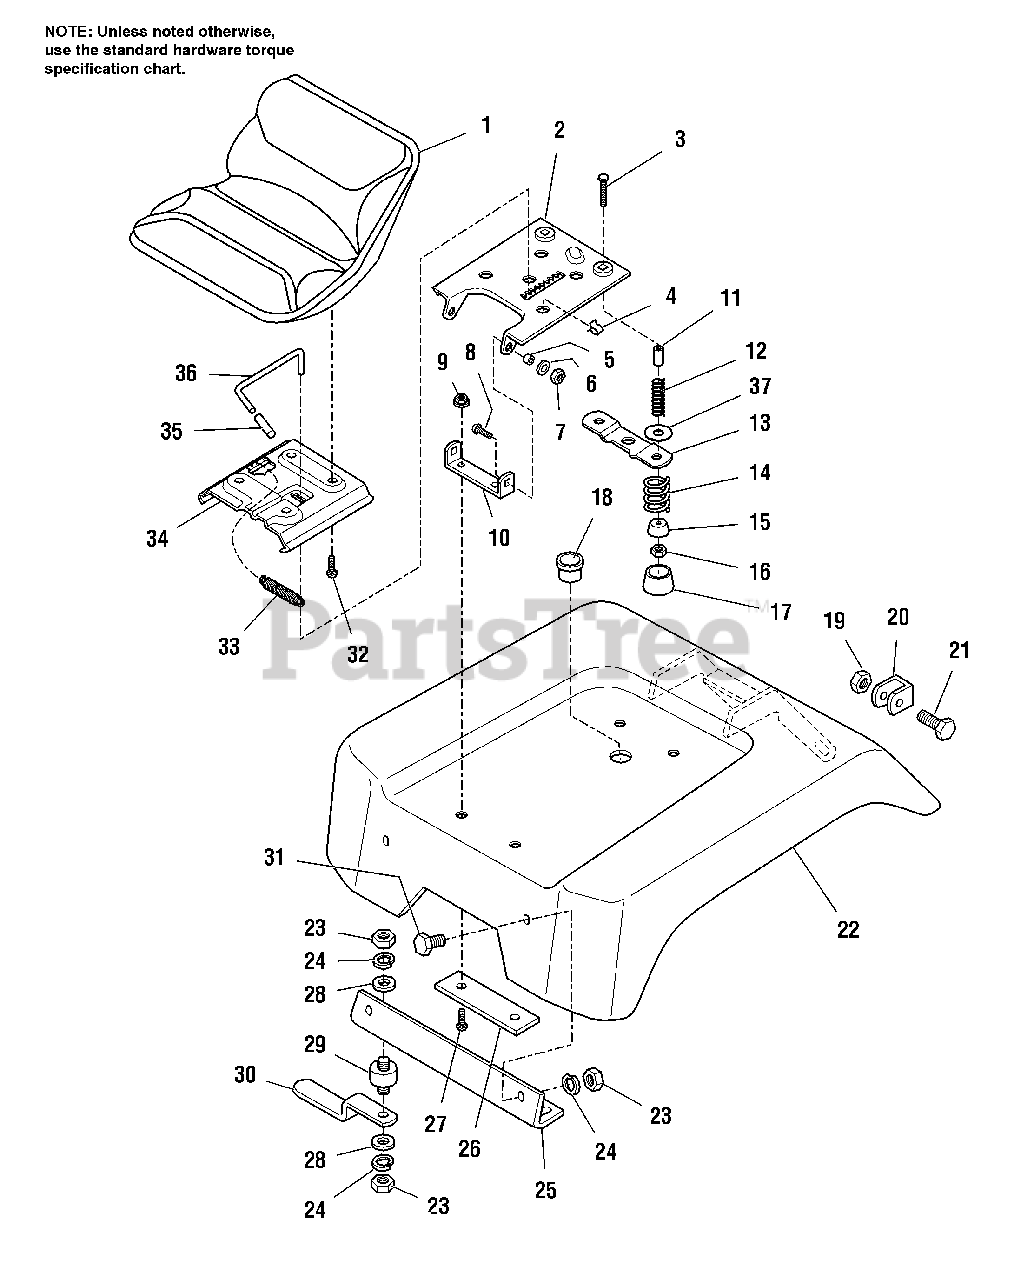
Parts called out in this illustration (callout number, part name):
2	SUPPORT, Seat Pivot
3	CARRIAGE BOLT, 5/16 -16 x 2 Lg
4	CLIP, Speed
6	WASHER, Plain
7	NUT, Hex Nylon Lock, 3/8-16
8	CARRIAGE BOLT, 3/8-16 x 1
9	NUT, Hex Flange, Whiz Lock, 3/8-16
10	BRACKET, Seat Pivot
12	SPRING, Compression
13	PLATE, Switch
14	SPRING, Compression (2 OD)
15	WASHER, Seat Spring
16	NUT, Hex Nylon Lock, 5/16-18
17	COVER, Spring
18	BUSHING, Snap
19	NUT, Hex Lock, 3/8-16
20	STOP, Seat Deck
21	CAPSCREW, Hex Hd, 3/8-16 x 1-1/4
22	DECK ASSEMBLY, Seat (Orange)
22	DECK ASSEMBLY, Seat (Red)
23	NUT, Hex, Full, 5/16-18
24	LOCKWASHER, 5/16
25	BRACKET, Front Seat Deck
26	PLATE, Reinforcement
27	CAPSCREW, Truss Head, Torx Drive, 3/8-16 x 1
28	WASHER, 11/32
29	CONNECTOR, Cushion
30	CLIP, Latch
31	CAPSCREW, Hex Hd, 5/16-18 x 5/8
32	CAPSCREW, Hex Flange Hd, Whiz Lock, 5/16-18 x 1/2
33	SPRING, Extension
34	SLIDE, Seat
35	GRIP, Lever
36	LEVER, Seat Release
37	WASHER, 5/8 x 1-1/4 x 1/16
